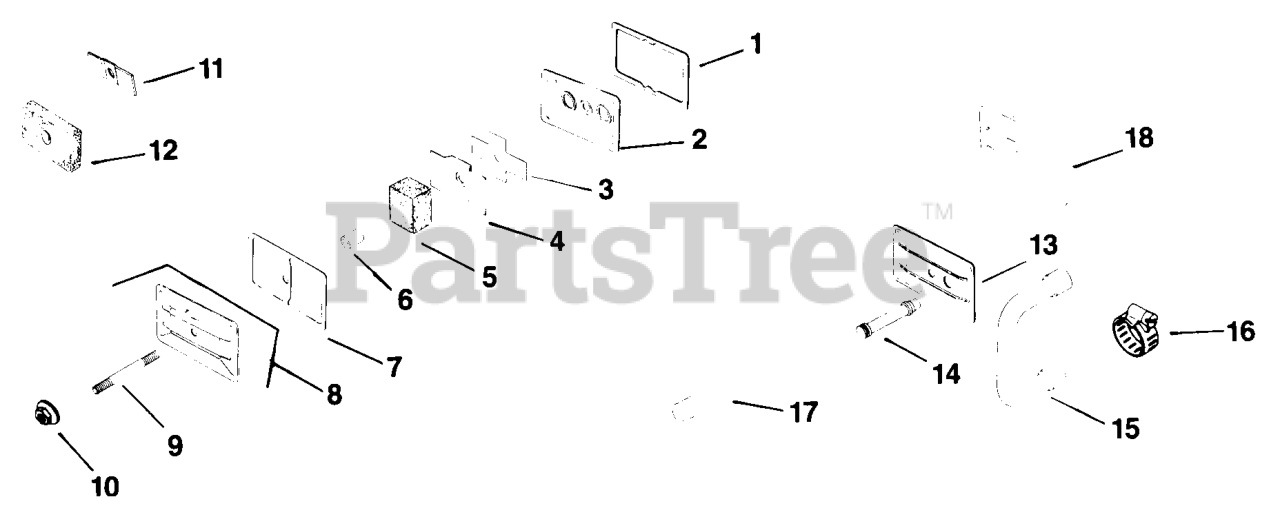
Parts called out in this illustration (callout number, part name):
1	GASKET, VALVE COVER
2	PLATE, BREATHER
3	REED, BREATHER - Use 47 402 01-S Breather Reed
4	BAFFLE, BREATHER
5	FILTER, BREATHER
6	SEAL, BREATHER
7	GASKET, VALVE COVER
8	KIT, COVER
9	STUD, 1/4-20x3-1/4" - DISCONTINUED
10	PALNUT, 1/4-20
